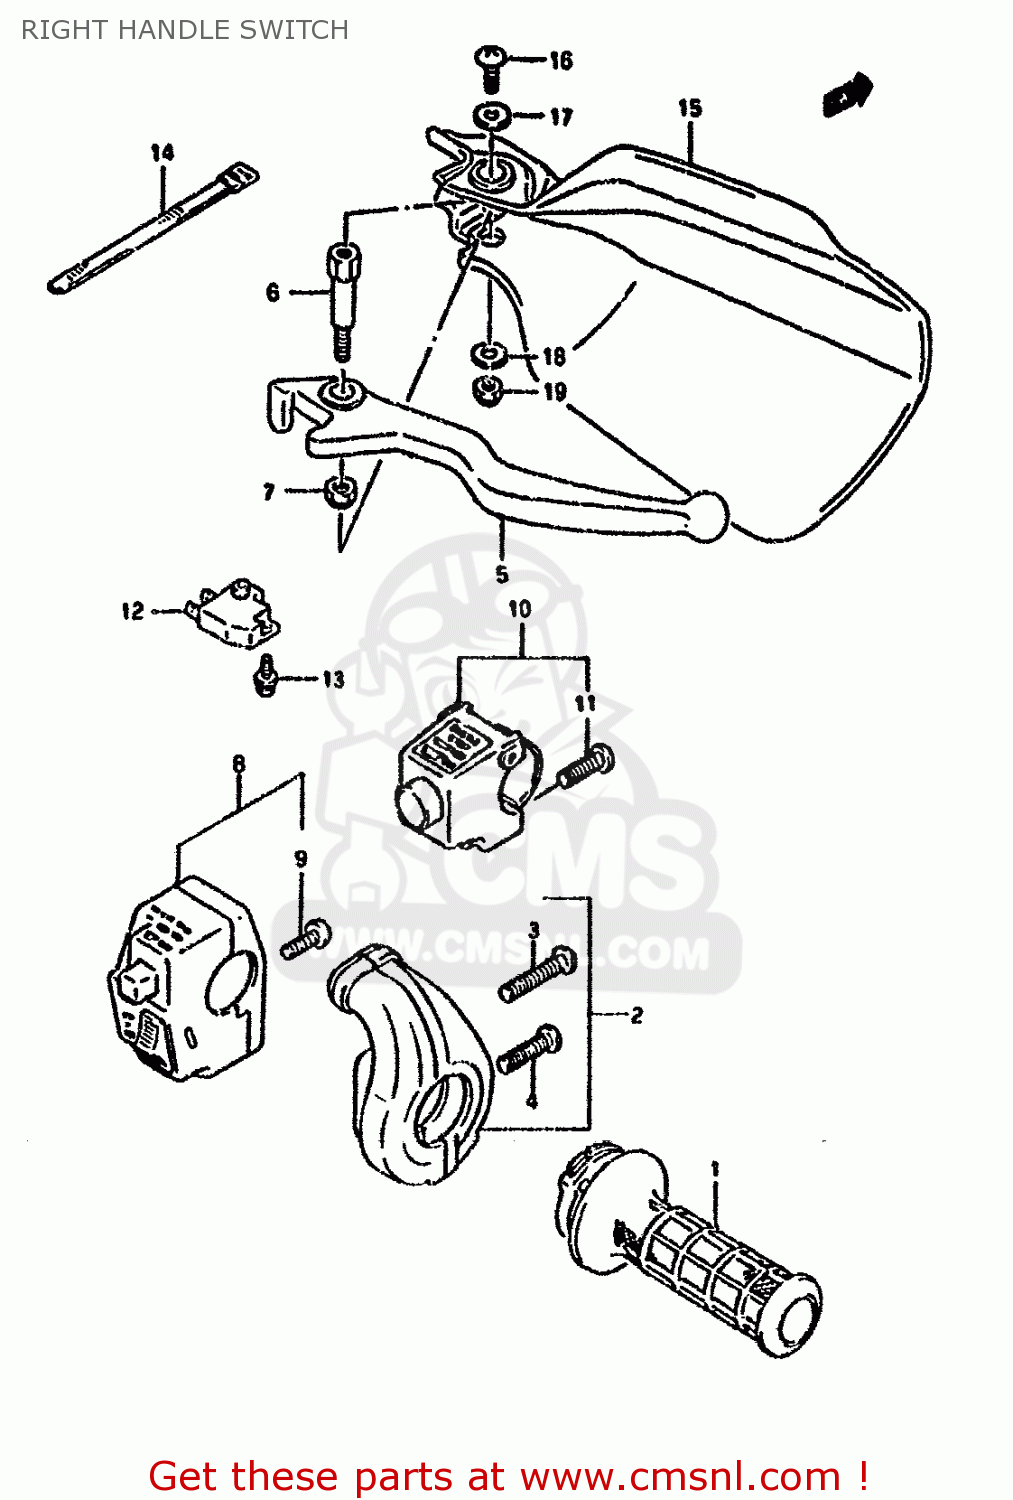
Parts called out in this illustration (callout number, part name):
1	GRIP,THROTTLE
2	CASE ASSY,THROTTLE
3	SCREW(5X25)
4	SCREW 5X20
5	LEVER,BRAKE
6	BOLT,BRAKE LEVER PIVOT
7	NUT
8	SWITCH ASSY,HANDLE RH
9	SCREW(5X25)
10	SWITCH ASSY, HANDLE RH
11	SCREW
12	SWITCH ASSEMBLY,STOP
13	SCREW
14	CLAMP(L:120)
15	COVER,KNUCKLE,R
16	SCREW
17	WASHER (5.5X16X1.2)
18	WASHER (6.5X17X1.6)
19	NUT 6MM
